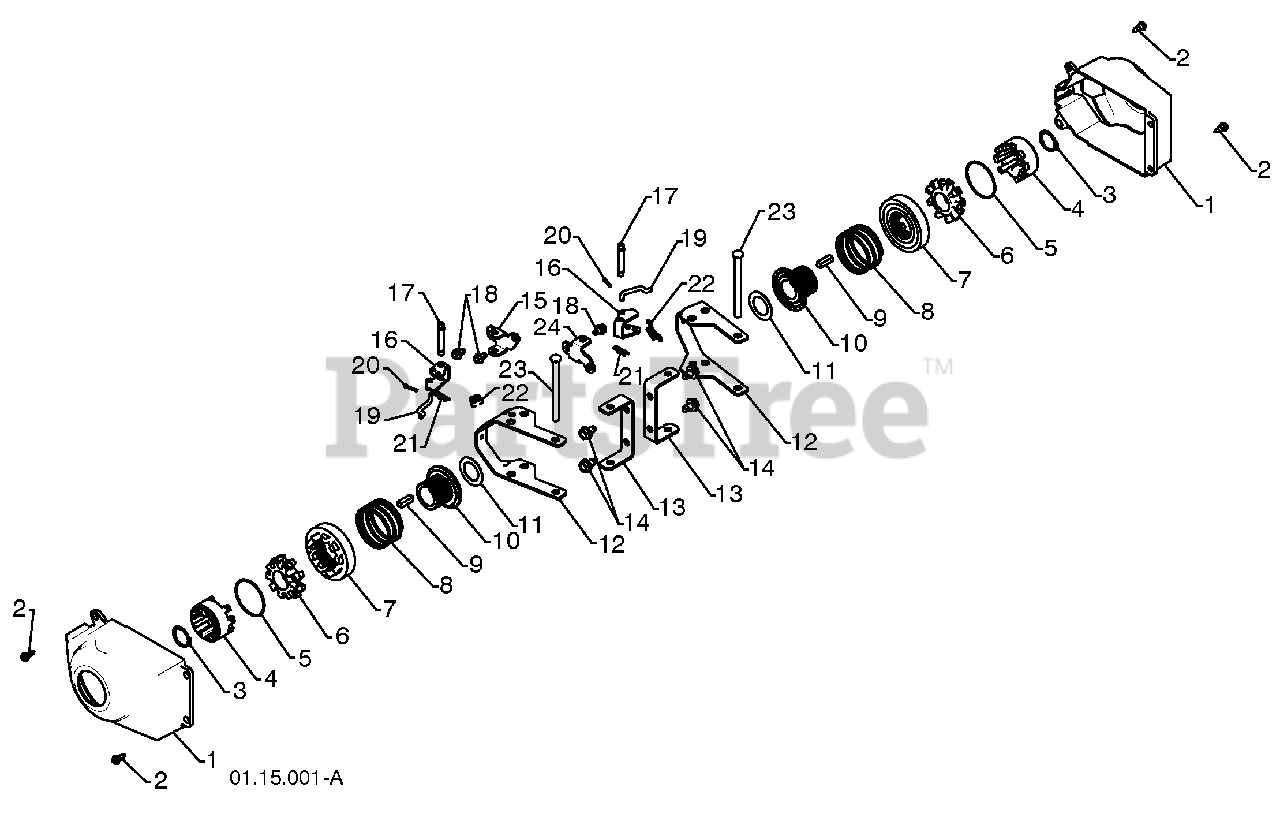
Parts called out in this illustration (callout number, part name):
1	COVER
2	SHOULDER SCREW
3	RETAINER RING
4	WHEEL DRIVER
5	RETAINER RING
6	WHEEL LOBE
7	CLUTCH SLIDE
8	SPRING
9	SQUARE KEY
11	THRUST WASHER
12	STEERING YOKE
13	STEERING BRACKET
14	SCREW 5/16-18 X .50
15	PIVOT BRACKET
16	BELLCRANK
17	BELLCRANK PIN
18	SCREW 1/4-20 X .375
19	STEERING LINK
20	RETAINER
21	RETAINER
22	SPRING
23	LEVER PIN
24	PIVOT BRACKET
